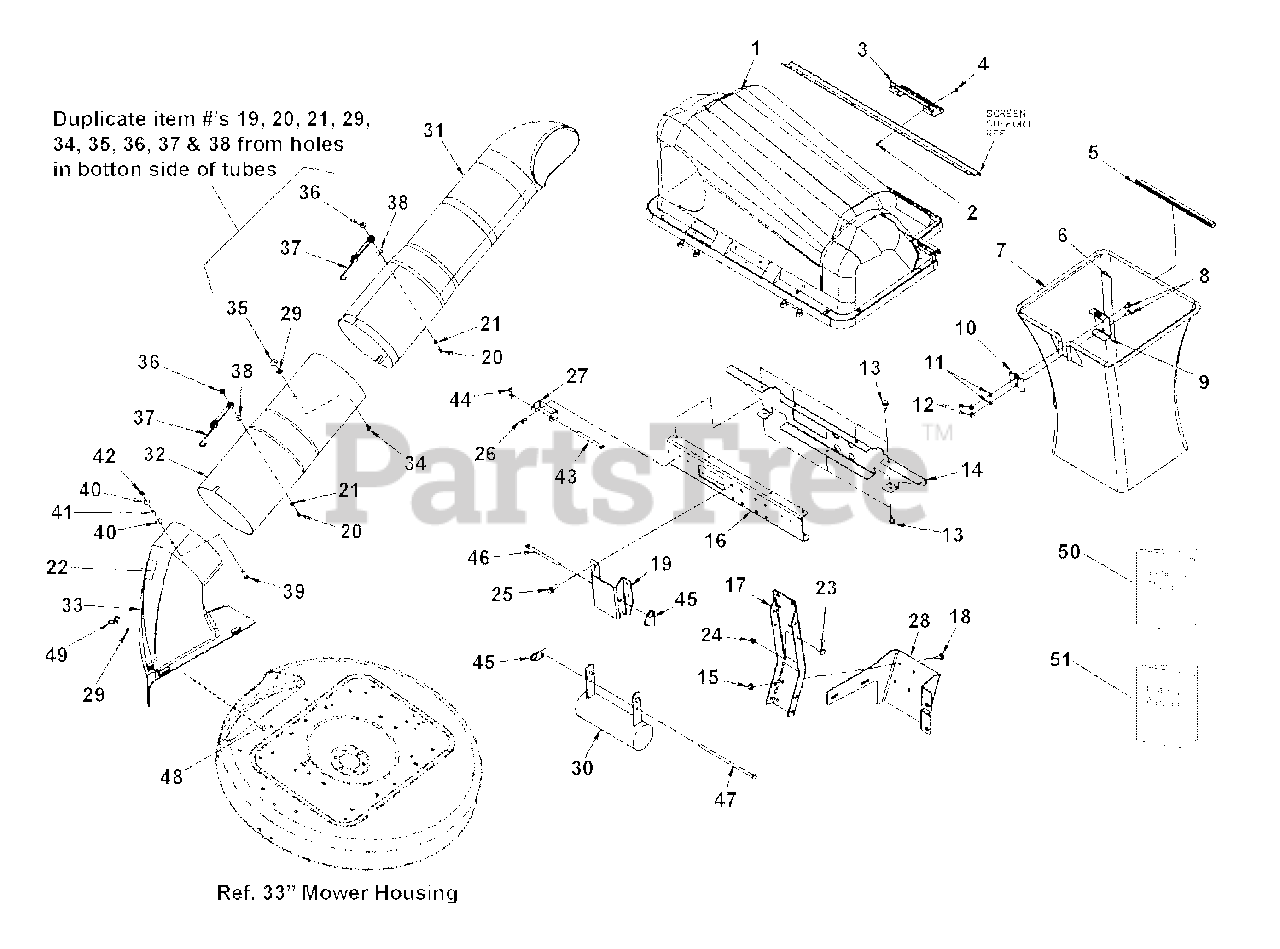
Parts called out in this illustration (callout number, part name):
1	COVER ASSY, Twin Catcher
2	SCREW, Truss HD Phillips #10-24X0.750
3	HANDLE, Plastic
4	NUT, Hex Lock 10-24 W/NYL Insert NC3B BLK
5	CLIP, Tube Grass Bag
6	BAG, Grass, 15.4X16X22.5 White Poly Cloth
7	HOOP, Twin Catcher .500DIA Yellow
8	BOLT, RD HD SH SQ NK 5/16-18X0.750 G5 BLK
9	HANGER, Grass Bag Hoop 10GA Twin - Black
10	CLAMP, 10GA For (2) .500DIA Rods - Black
11	WASHER, Spring Lock, .312 BLK
12	NUT, Hex 5/16-18 NC-2B BLK
13	SCREW, Hex Washer Head Taptite 5/16-18X0.750 BLK
14	BRACKET, Tab Cross Sup Twin - Black
15	NUT, Hex Flange 3/8-16 Whiz Lock - BLK
16	CHANNEL, Cross Support - Black
17	SUPPORT, Upright - Black
18	SCREW, Hex WZ Lock Flange 3/8-16X0.750 BLK
19	BRACKET, Bagger Mount ZT 2007 - Black
20	SCREW, Pan Head Machine, CR, #10C X5/8 GR5 YZ
21	WASHER, .219X.5X.049 BZ
22	DECAL, Chute Deflector
23	BOLT, Shoulder 5/16-18 0.56LG .49SH .25L YEL
24	NUT, Hex Flange 5/16-18 Two-Way Lock
25	SCREW, Hex Washer Head Taptite 3/8-16X1.000 BLK
26	SCREW, Hex Washer Head Taptite 1/4-20X0.500 BLK
27	PIVOT, Hinge
28	HITCH, Bagger ZT - Black
29	WASHER, 5/16" YZ
30	WELD, Weight Assembly
31	TUBE, Upper, Twin Bagger, 38" & 42" RZ
32	TUBE, Lower, Twin Bagger, 44"/50" RZT
33	ADAPTER, 33" Grass Catcher (Incl. Decal Item #34)
34	SCREW, Pan Head Machine, 5/16C X5/8 GR5 YZ
35	NUT, "T", 5/16C YZ
36	WELD NUT, #10C YZ
37	STRAP, Mounting Bag Adapter
38	WASHER, .192X.75X.051 YZ
39	SCREW, Pan Head Phillips, 1/4-20X1.50
40	WASHER, 0.187(0.19IDX0.75ODX.06THK)
41	SPACER, 0.256 ID X 0.394 OD X 0.512 LG
42	NUT, Hex Flange 1/4-20 ESNA BLK
43	PIN, Cover Hinge .375DIA 3.75 LG YEL
44	CLIP, Hair Pin .093DIA SPG WR1.625LG
45	RETAINER, Pin Spring For .312/.375 Pin BLK
46	PIN, Hinge, Drilled .375 X 5.34L YEL
47	ROD, Hinge 5/16" x 9.69"
48	BOLT, RHSSN, 5/16C X1 GR5 YZ
49	NUT, Wing Lock, 5/16C YZ
50	MANUAL, Operators, SMI/Snapper 33" Twin ZT Bagger
51	MANUAL, Illustrated Parts List, Simplicity 33" Twin ZT Bagger
